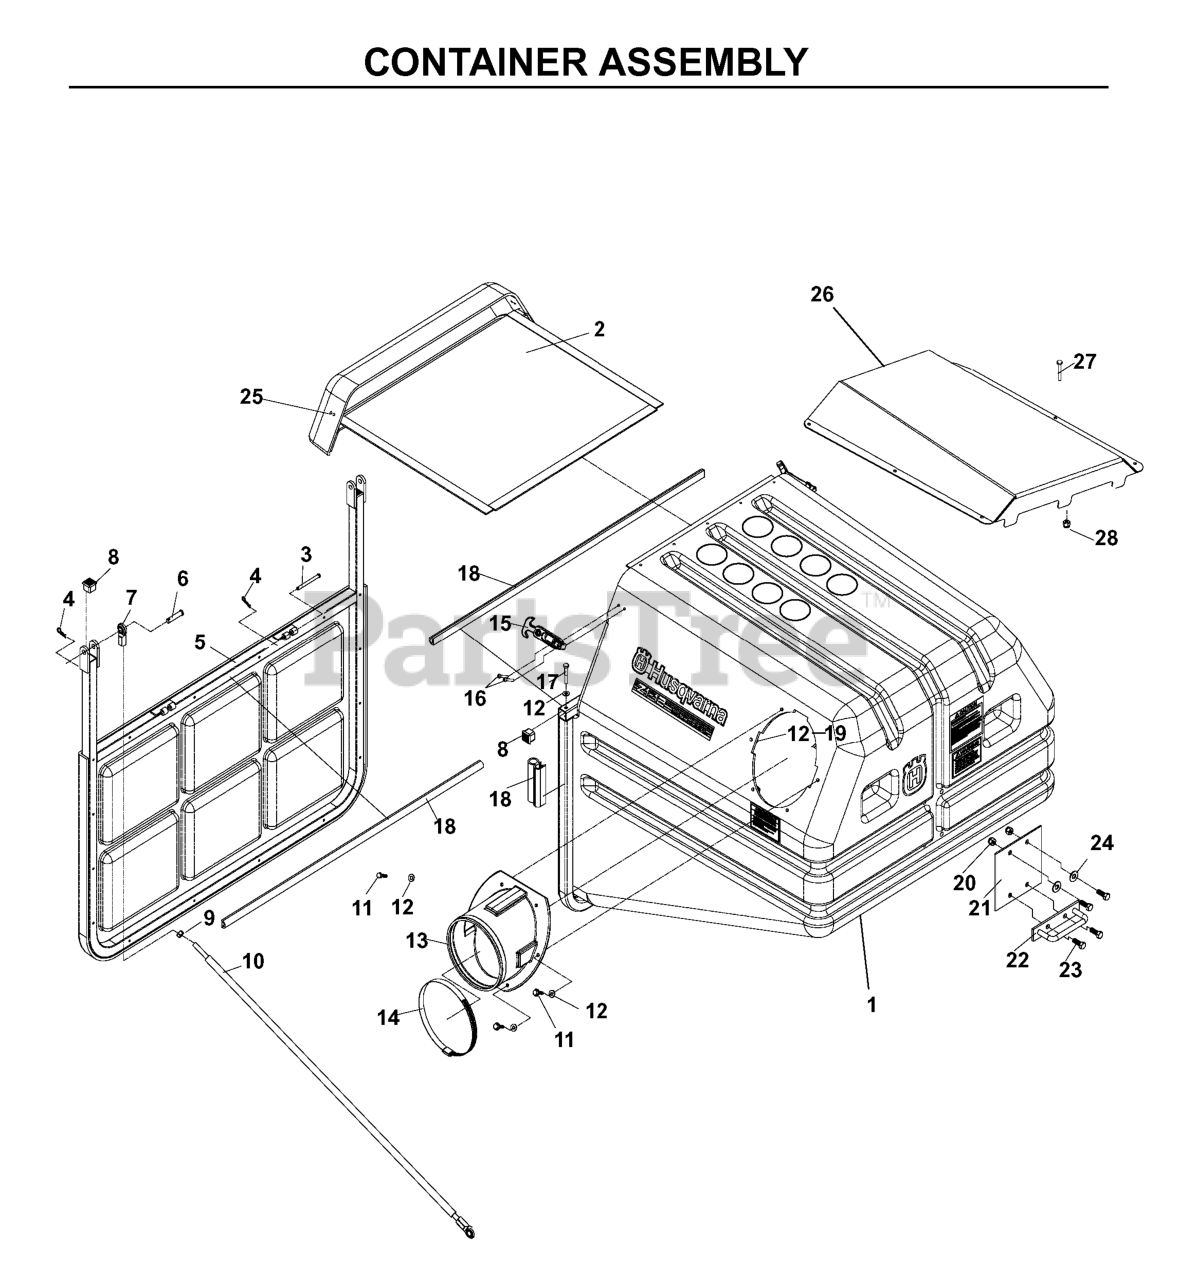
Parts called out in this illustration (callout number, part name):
2	ASSEMBLY, EXHAUST, Z1-12
3	CLEVIS PIN
4	PIN, HAIR COTTER #13 5/64 X 1
6	PIN
7	ROD END
8	FINISHING PLUG
9	HEX NUT 3/8-24
10	PAINTED ARM BLACK
11	BOLT, 1/4-28 X 1
12	WASHER, 1/4
14	HOSE CLAMP
16	PANHEAD SCREW
17	BOLT 1/4-20 X 2"
18	SVC KIT, DOOR SEAL
19	Nut, Hex, Nylon Lock, 1/4"-20
20	NUT 3/8 NYLOC
21	BACK PLATE
22	CONTAINER LATCH WELDMENT BLACK
23	BOLT, 3/8-16 X 1
24	WASHER, 3/8
25	LATCH BASE
26	HOOD WLDMT - Z12
27	SCR #10-24 X 3/4
28	NUT 10-24 NYLOC
540002004	Nut, Hex, Nylon Lock, #10-24
